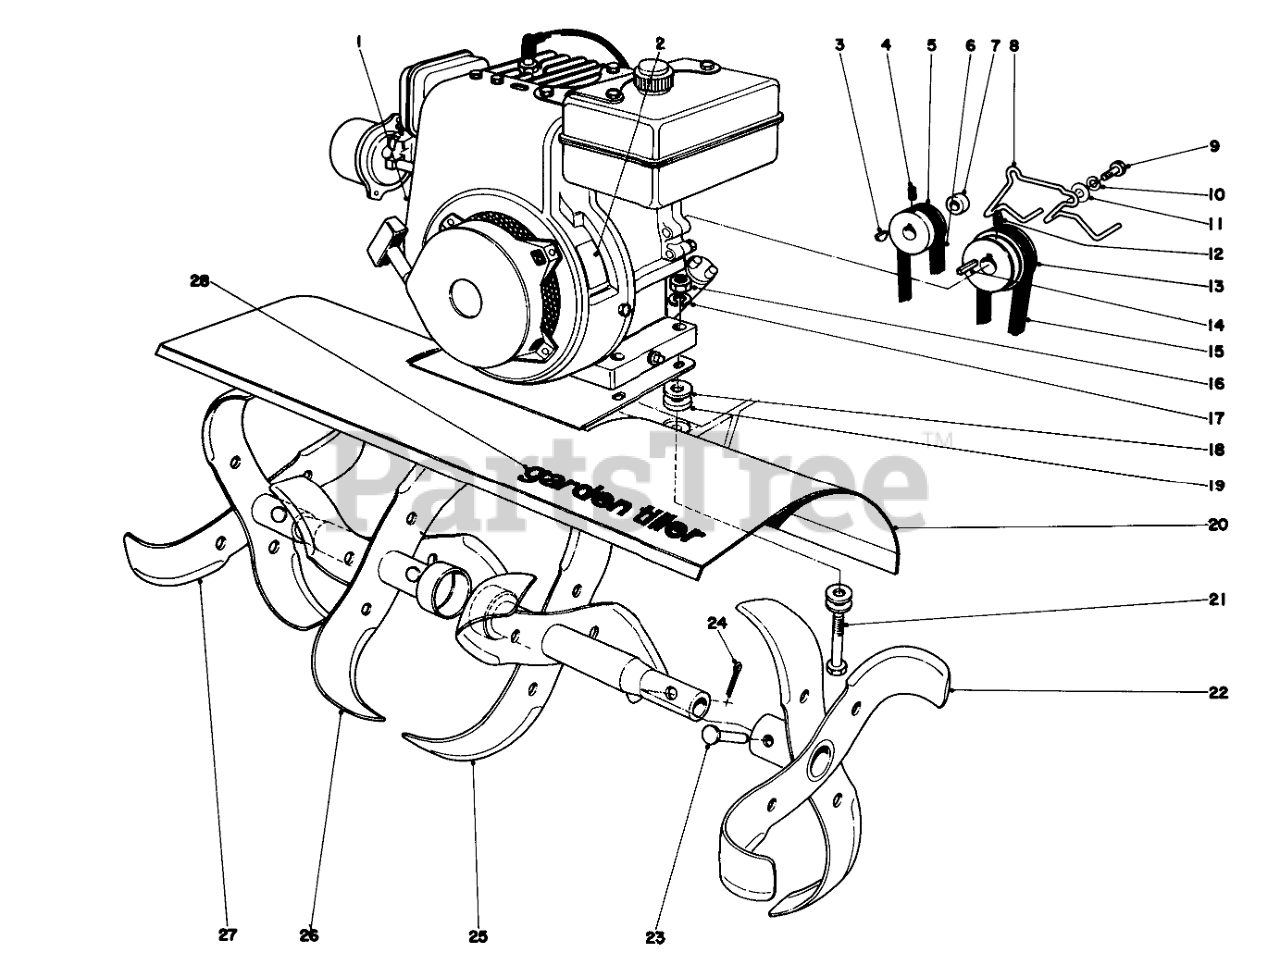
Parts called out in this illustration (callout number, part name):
1	Engine
2	Toro Lubrication
3	HI PRO KEY
4	Set Screw
5	PULLEY
6	Belt Reverse
7	Spacer
8	Belt Guide Upper
9	SCREW-HH
10	WASHER-LOCK
11	WASHER-FLAT
12	SCREW-SET, HSH
13	Engine Pulley
15	Belt
16	NUT-HEX
17	WASHER-LOCK
18	WASHER-FLAT
19	WASHER-FLAT
20	Shield
21	SCREW-HH
22	LH OUT SLASH TINE WA
23	TINE PIN
24	PIN-COTTER
25	Inner Tine L.H.
26	Inner Tine R.H.
27	RH OUT SLASH TINE EA
28	Decal
